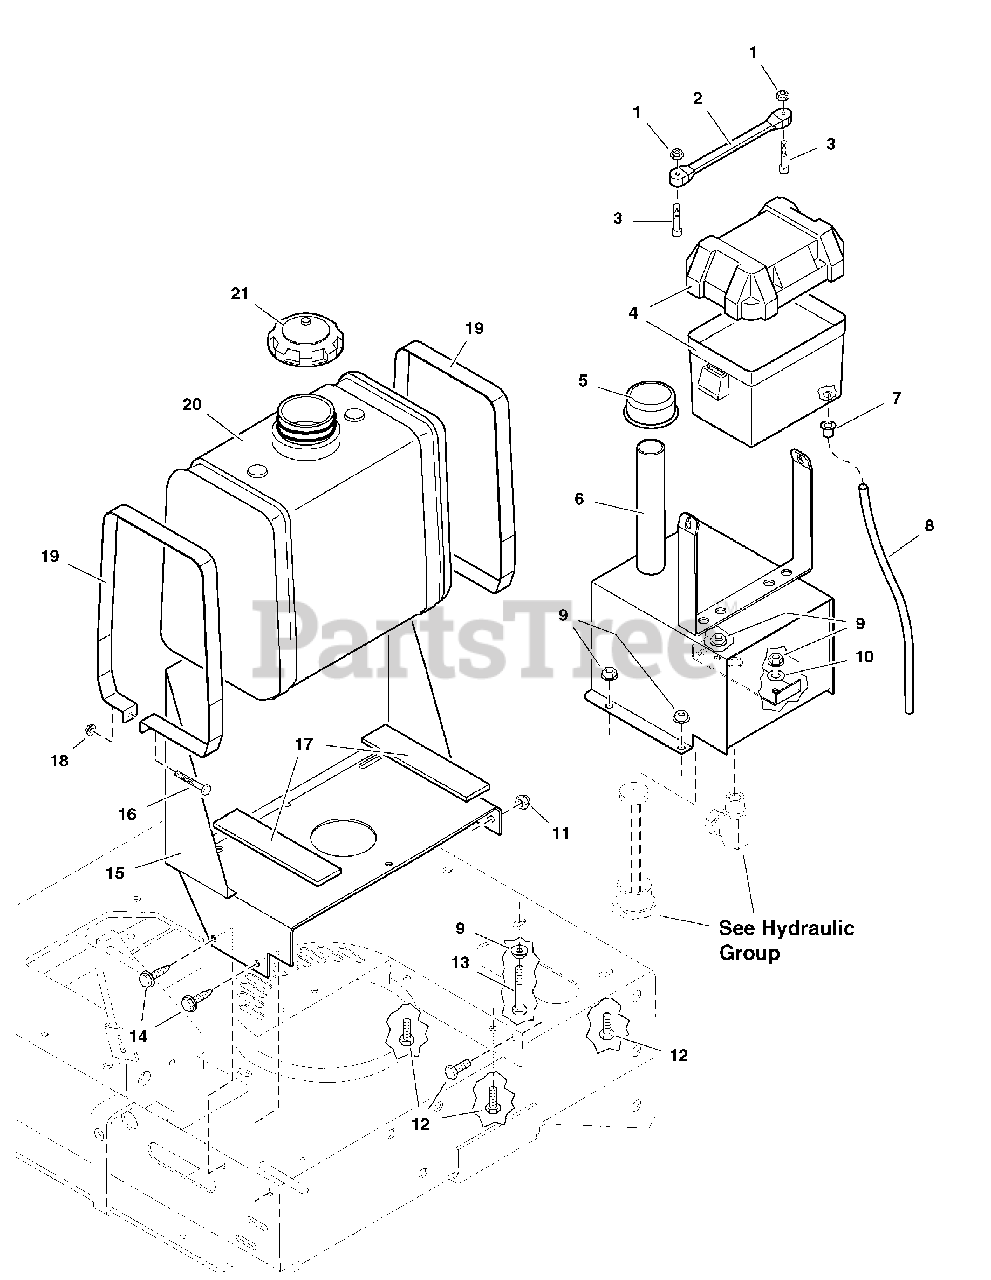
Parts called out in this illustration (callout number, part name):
1	NUT, Hex, Nylon Lock, #10-24
2	RUBBER STRAP
3	SCREW, Phillips Hd, #10-24 x 1
4	BATTERY BOX
6	HYDRO TANK ASSEMBLY, complete (includes Ref 5, decal and fittings)
7	RUBBER BUSHING
9	NUT, Hex, Serrated Flange, 5/16-18
10	WASHER, 5/16
11	NUT, Hex, Nylon Lock, 5/16-18
12	CAPSCREW, Hex Hd, 5/16-18 x 3/4
13	CAPSCREW, Hex Hd, 5/16-18 x 1-3/4
14	CAPSCREW, Hex Hd, Self Tapping, 5/16-18 x 3/4
15	FUEL TANK MOUNT
16	CAPSCREW, Hex Hd, 1/4-20 x 1-1/4
18	NUT, Hex, Serrated Flange, 1/4-20
19	FUEL TANK STRAP
20	TANK, FUEL, PLASTIC, 6 GALLON, W/ FUEL LINE
21	FUEL TANK CAP
